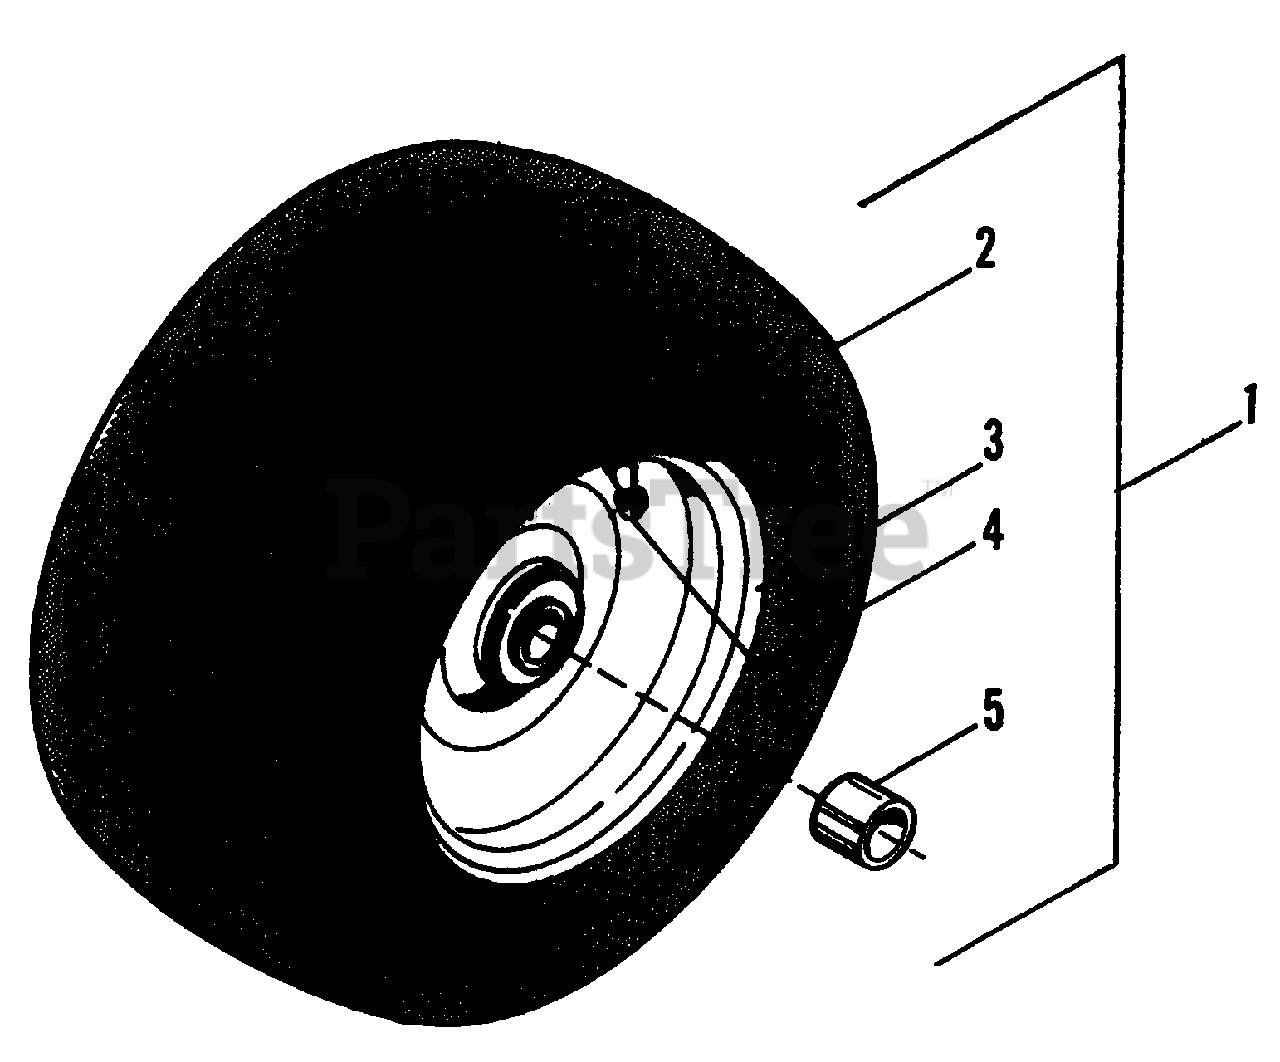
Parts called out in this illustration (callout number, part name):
1	WHEEL & TIRE ASSY, 16 x 6.50-8, 4 Ply
2	TIRE, 16 x 6.50-8, 4 Ply
3	RIM ASSY.
4	VALVE STEM & CAP
5	BEARING, Cup
